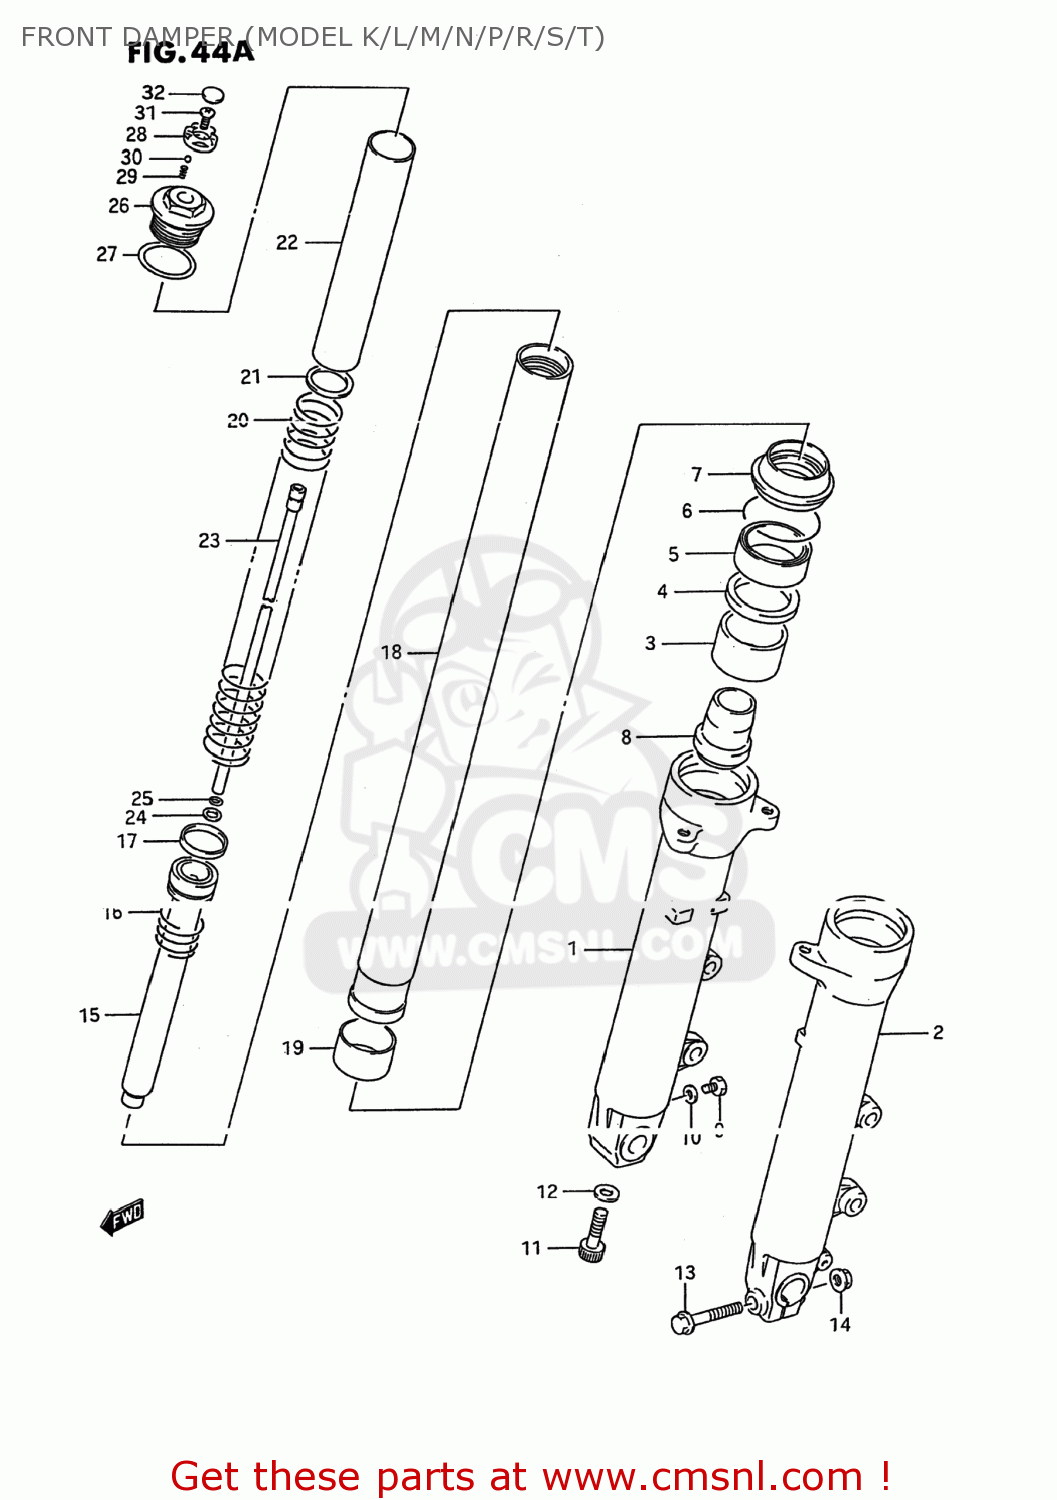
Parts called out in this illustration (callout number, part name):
1	TUBE,OUTER,RIGHT
2	TUBE,OUTER,LEFT
3	BUSH,GUIDE
4	SPACER,SEAL
5	SEAL,OIL
6	CIRCLIP,FORK OIL SEAL
7	BOOT
8	PIECE,OIL LOCK
9	BOLT(6X8)
10	GASKET,DRAIN,PLUG (NAS)
11	BOLT(8X27)
12	GASKET (NAS)
13	BOLT
14	NUT
15	SEAT,UNDER
16	SPRING,REBOUND
17	RING,PISTON
18	TUBE,INNER
19	BUSH,SLIDE
20	SPRING,MAIN
21	JOINT,SPRING
22	SPACER,SPRING
23	ROD,INNER
24	WASHER
25	O RING
26	BOLT,FORK
27	O RING
28	PLATE,ADJUSTER
29	SPRING
30	BALL
31	SCREW
32	CAP
